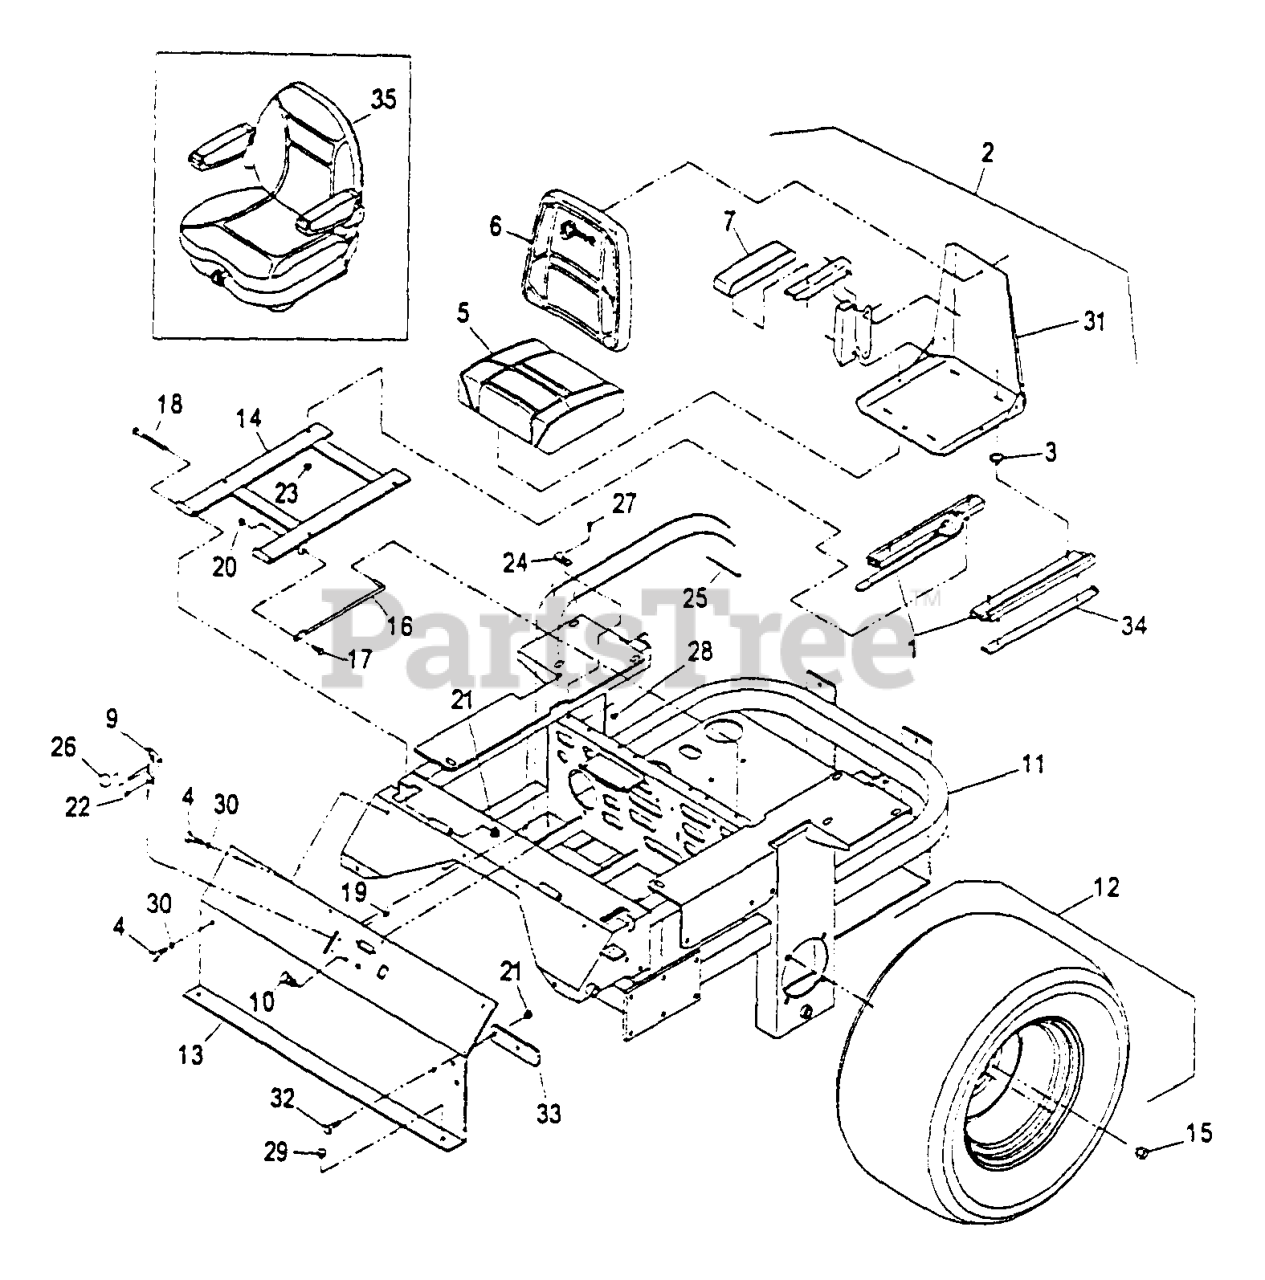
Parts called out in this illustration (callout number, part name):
1	TRACK-SEAT
3	SPACER-TRACK
9	THROTTLE CABLE ASM
10	CONTROL-CHOKE
13	Front, Console
16	ROD-HOLDUP, SEAT
22	BOLT-CARR
24	CLIP-LOOM
25	TIE-PLASTIC
26	KNOB-BALL
31	FRAME-SEAT
33	STOP-BRAKE, PARK
34	STOP-SEAT
